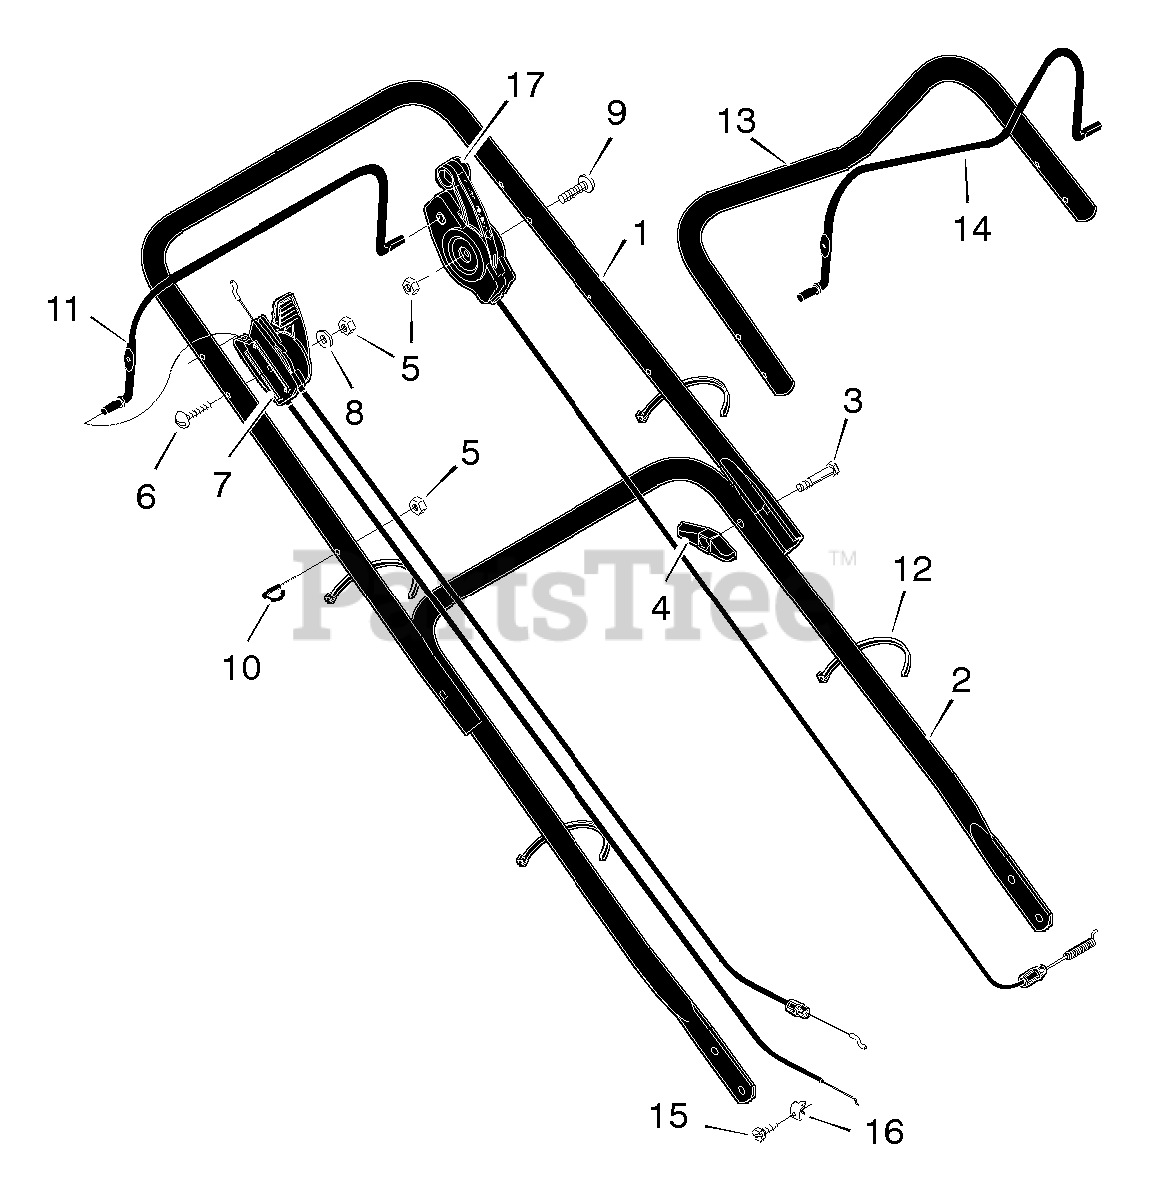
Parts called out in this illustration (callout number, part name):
1	Handle, Upper-Straight (Black)
2	Handle, Lower (Black)
4	Knob, Plastic
5	Locknut
7	Throttle Control and Stop Cable
8	Washer
10	GUIDE, ROPE
11	Stop Lever - Straight
12	Fastener, Cable
13	Handle, Upper-Curved (Black)
14	Stop Lever - Curved
15	Screw *
16	Clamp
17	Drive Control
